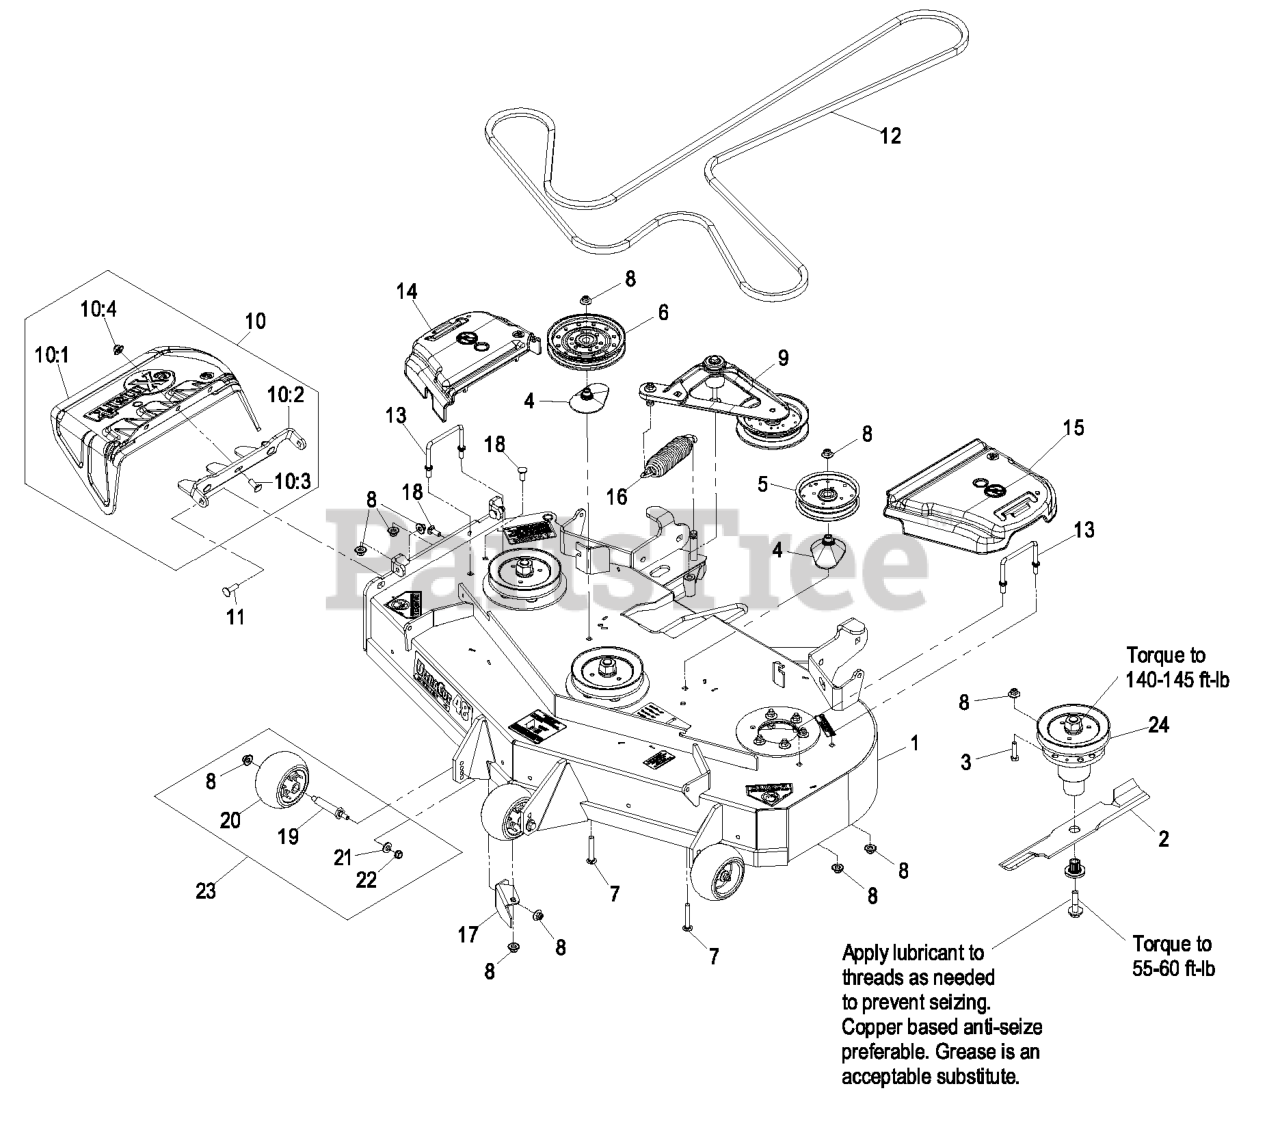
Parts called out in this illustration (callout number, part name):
1	ASM,DECK W/DECALS 484
3	SCREW-HH
4	SPACER-PULLEY
5	PULLEY-IDLER
7	SCREW-CARR
8	Nut-Nyloc 3/8-16 Flg
10	ASM,DISCHARGE CHUTE
10:1	CHUTE,DISCHARGE
10:2	BRACKET,DISCHARGE CHUTE
10:3	SCREW-CARR
10:4	Nut-Nyloc 3/8-16 Flg
11	Bolt-Carriage 3/8-16 X 1 1/4
12	BELT
13	WIREFORM-COVER
14	COVER-BELT, RH
15	COVER-BELT, LH
17	BAFFLE,DISCHARGE
18	SCREW-CARR
20	ROLLER-SCALP, ANTI
21	WASHER-BELLEVILLE
22	NUT-HHF, WHIZ
24	KIT,CUTTER HOUSING 48
25	Asm, Deck Complete 484
